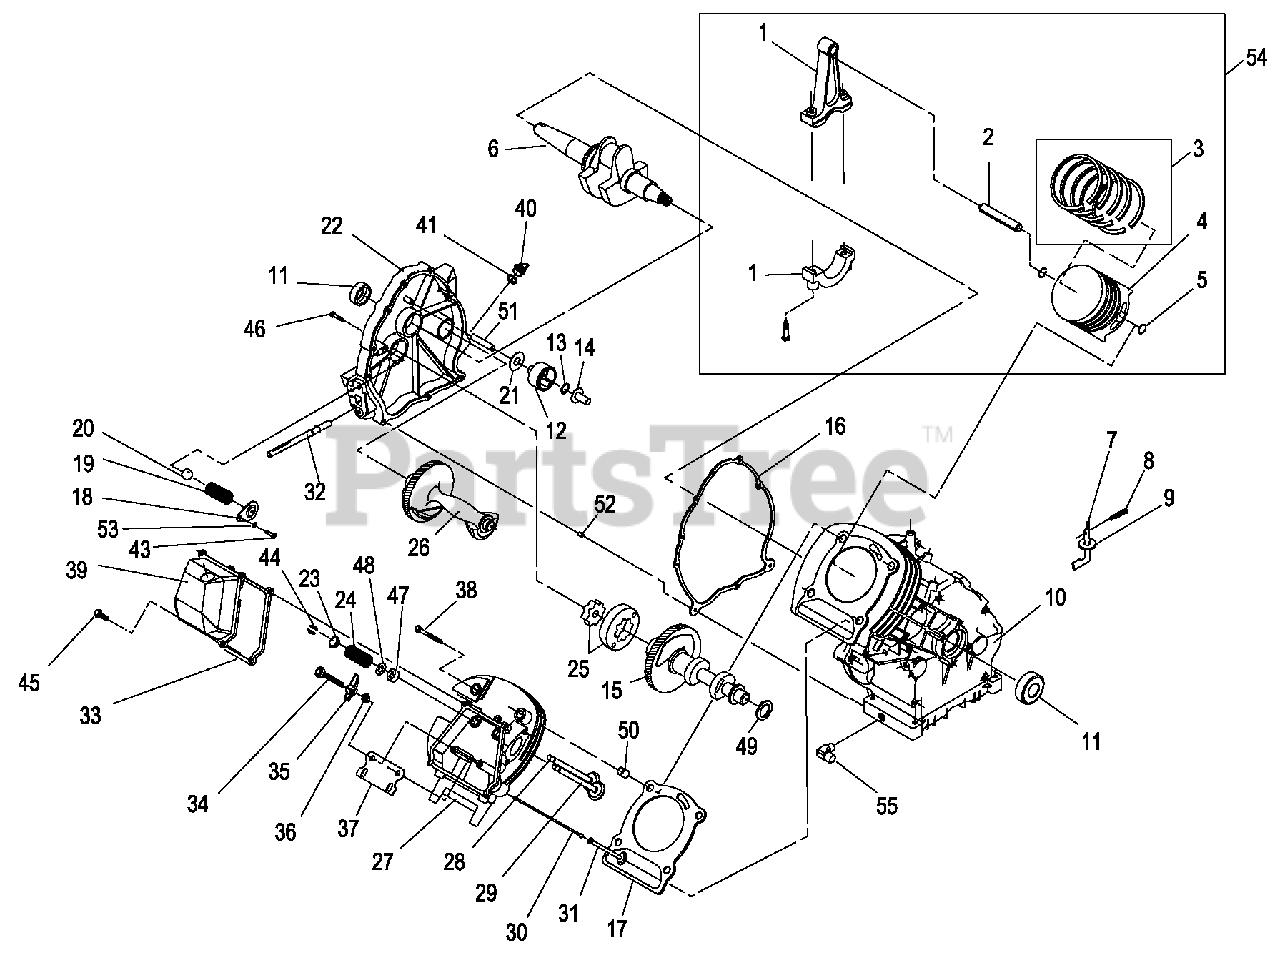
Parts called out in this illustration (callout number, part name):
1	ASSEMBLY, CONNECTING ROD
2	PIN, PISTON D20
3	RING SET, PISTON dia90
4	PISTON FLAT TOP 90 HSB 2013
5	RETAINER, PISTON PIN 20
6	ASSY CRANKSHAFT 410 SAE TAPER
7	ARM, GOVERNOR RC45
8	PIN, "R" GOVERNOR ARM
9	WASHER, GOVERNOR ARM THRUST
10	CRANKCASE, SUBASSEMBLY WITH PLUGS GH410
11	SEAL, 35 I.D. CRANKSHAFT
12	ASSEMBLY, GOVERNOR GEAR
13	C-RING, GOVERNOR GEAR RETAINER
14	SPOOL, GOVERNOR- MACHINE
15	CAMSHAFT ASSEMBLY
16	GASKET , CRANKCASE
17	GASKET, HEAD 410
18	COVER, OIL PRESSURE RELIEF
19	SPRING, OIL RELIEF 360
20	BALL, DIA 11/32 PRESSURE RELIEF
21	WASHER, THRUST GOVERNOR GEAR
22	ASSEMBLY, COVER, GEAR TOP CHECK / FILL
23	RETAINER, VALVE SPRING
24	VALVE SPRING
25	SET,GEROTOR 12 THK
26	BALANCER
27	ASSEMBLY,CYLINDER HEAD SEATS & GUIDES
28	VALVE, EXHAUST
29	VALVE, INTAKE
30	PUSH ROD 174.9
31	TAPPET
32	ASSEMBLY, SCREEN OIL PICK-UP
33	GASKET, ROCKER COVER 410
34	STUD, D20 PIVOT BALL
35	ROCKER ARM
36	NUT, JAM (ROCKER ARM)
37	PLATE, PUSH ROD GUIDE
38	SCREW, HHFL M10-1.5 X 105
39	ASSEMBLY, ROCKER COVER BREATHER OHVI
40	PLUG, OIL FILL PLASTIC, ORANGE
41	O-RING 17.8 I.D. x 2. 4
43	SCREW HHC M5 - 0.8 X 10 C8.8
44	KEEPER, VALVE SPRING
45	SCREW HHFCS M6-1 X 12
46	SCREW, HHFC M8-1.25 X 42
47	SEAL, VALVE STEM D7
48	WASHER, VALVE SPRING
49	WASHER, LARGE SPRING
50	SLEEVE, DOWEL PIN 14 DIA.
51	SHAFT, GOVERNOR RC55
52	SLEEVE, DOWEL PIN 12 DIA.
53	WASHER LOCK M5 RIBBED
54	ASSY PISTON FLAT TOP GT999
55	BARBED EL 90 3/8NPT X 3/8
